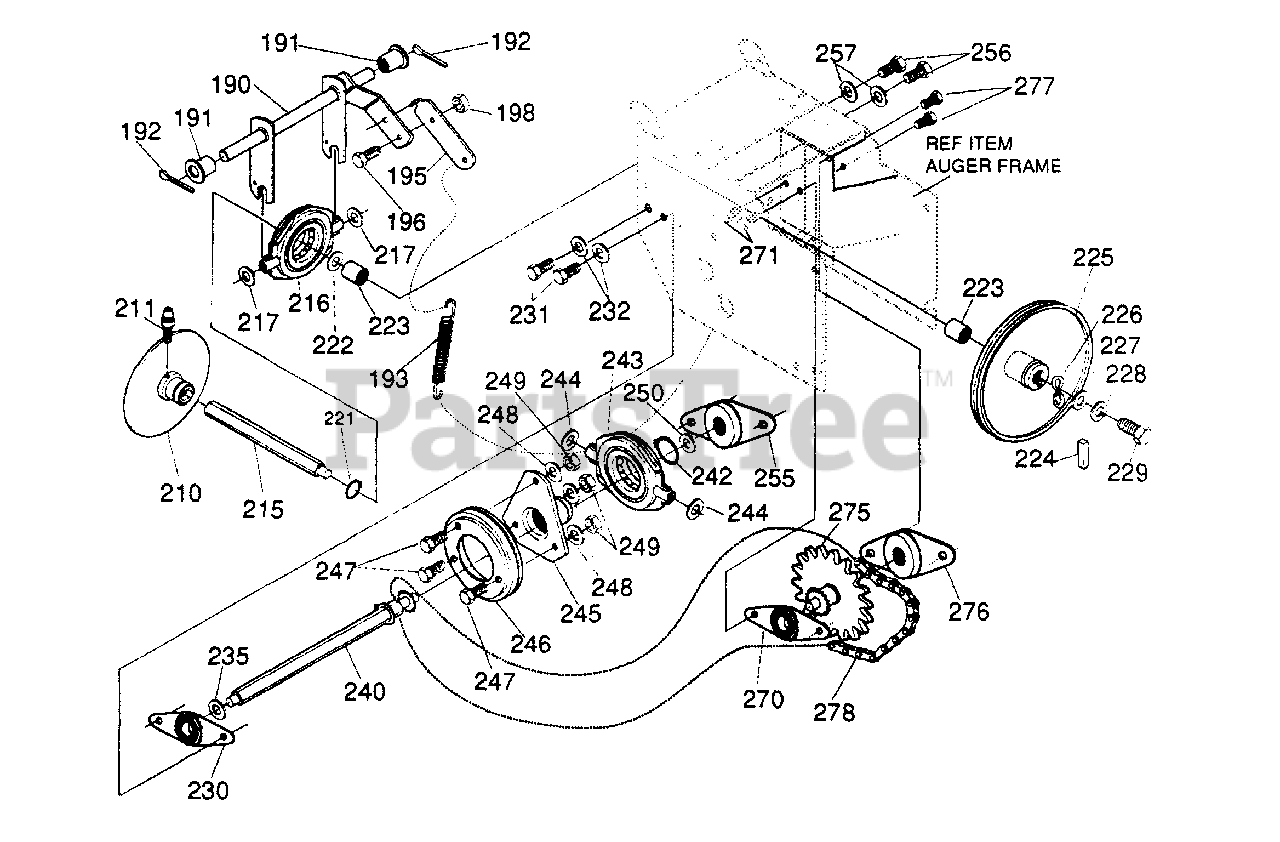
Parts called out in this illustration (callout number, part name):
190	LEVER, ASSY TRACT CLUTCH
191	BEARING, FLANGED
192	PIN, COTTER .125 DIAx1.00 LG
193	SPRING, RETURN
195	LEVER, SPRING TRAC CL
196	SCREW, 1/4-20x.63
198	NUT, 1/4-20 REGHEXCTRLK
210	DISC, ASSY FRICTION WHEEL
211	ZERK, GREASE .25-28x1.12 LONG
215	SHAFT, HEX TRACTION
216	BEARING, TRUNION 1.25 ID
217	FLATWASHER, .505x1.00x.06
221	RING, RETEX1.16x.05
222	FLATWASHER,.680x1.12x.060
223	BEARING, BALL 6203-2AA
224	KEY, SQUARE. 18 SOx.63 LONG
225	PULLEY, V3L- 6.50x.56
226	WASHER, WAVE .675x1.00x.020
227	FLATWASHER, .281x1.00x.063
228	WASHER, SPTLK.263x.49x.07
229	SCREW, 1/4-20x.75
230	BEARING & RETAINER ASSY
231	SCREW, 5/16-18x.50 WAHHTAP
232	WASHER, SPTLK.328 X.60X.09
235	WASHER, SP .502X .75X.0605
240	SHAFT & SPRKT, ASSY #40-8T
242	RING, RETEX 1.16X.05
243	BEARING, TRUNION 1.2.5 ID
244	FLATWASHER,.505X1.00X.06
245	HUB, FRICTION WHEEL
246	WHEEL, FRICTION DISC 4.375 OD
247	SCREW, 1/4-20X .63
248	WASHER, SPTLK.26 X.50X.06
249	NUT, 1/4-20 REGHEX
250	WASHER, SP .502X .75X.0605
255	BEARING & RETAINER ASSY
256	SCREW, 5/16-18X .50
257	WASHER, SPTLK.328 X.60X.09
270	BEARING & RETAINER ASSY
271	SCREW, 5/16-18X .50
275	SPROCKET, ASSY 8T & 36T-41
276	BEARING & RETAINER ASSY
277	SCREW, 5/16-18X .50
278	CHAIN, ROLLER #42x40
